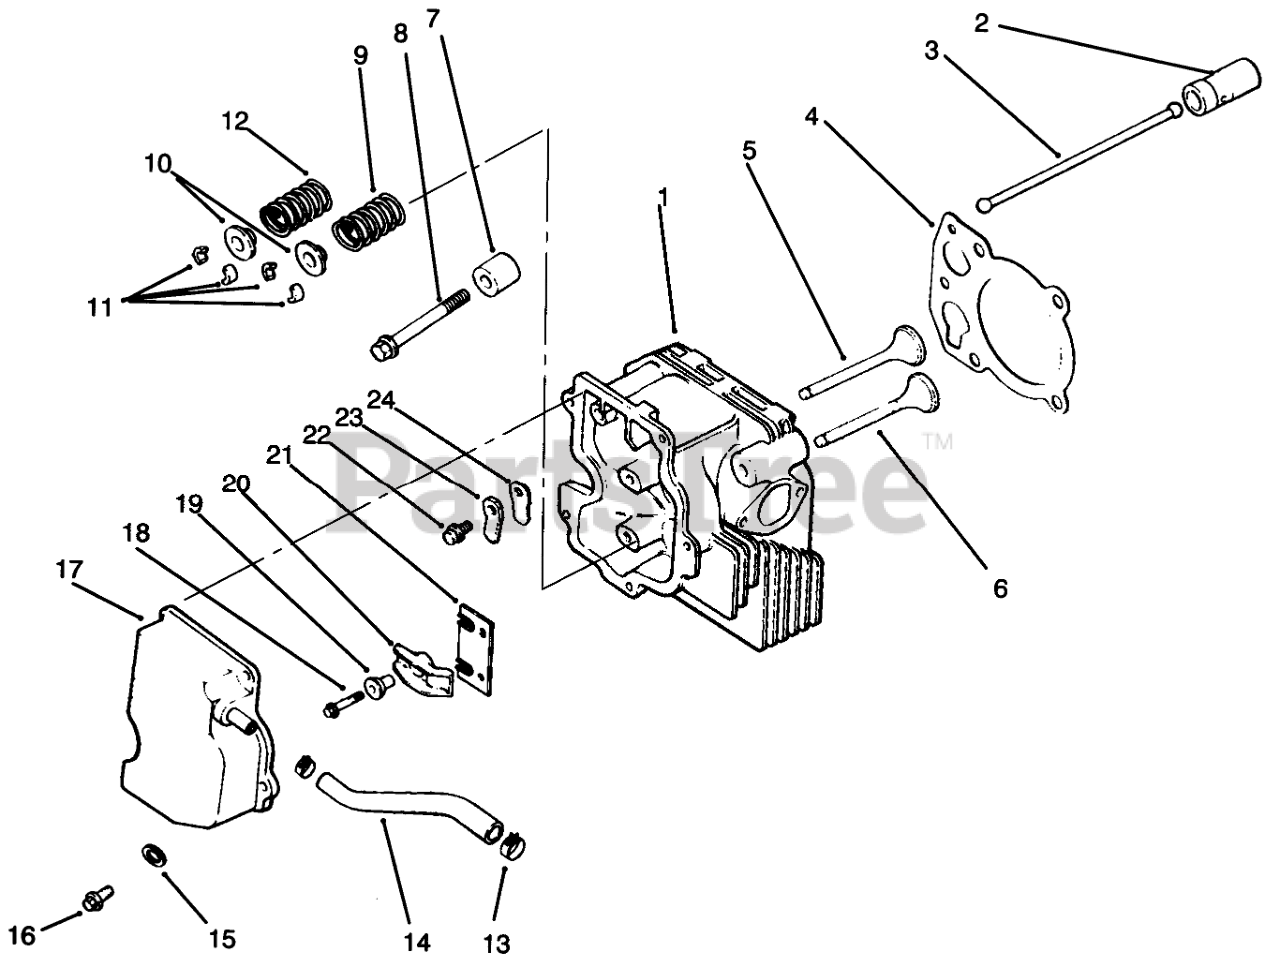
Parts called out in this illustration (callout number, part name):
1	Cylinder Head (Only On: 72042, 72043, 72062, 72063)
2	Lifter-Valve (Only On: 72042, 72043, 72062, 72063)
3	Rod-Push (Only On: 72042, 72043, 72062, 72063)
4	Gasket-Cylinder Head (Only On: 72042, 72043, 72062, 72063)
5	Valve-Intake STD (Only On: 72042, 72043, 72062, 72063)
5	Valve-Intake .25 (Only On: 72042, 72043, 72062, 72063)
6	Valve-Exhaust STD (Only On: 72042, 72043, 72062, 72063)
6	Valve-Exhaust .25 (Only On: 72042, 72043, 72062, 72063)
7	Spacer-Head Bolt Exhaust (Only On: 72042, 72043, 72062, 72063)
8	Screw M10x1.5x80 (Only On: 72042, 72043, 72062, 72063)
9	Spring-Valve Exhaust (Only On: 72042, 72043, 72062, 72063)
10	Cap-Valve Spring (Only On: 72042, 72043, 72062, 72063)
11	Kit-Retainer (Only On: 72042, 72043, 72062, 72063)
12	Spring-Valve Intake (Only On: 72042, 72043, 72062, 72063)
13	Clamp-Hose (Only On: 72042, 72043, 72062, 72063)
14	Hose-Breather (Only On: 72042, 72043, 72062, 72063)
15	Washer-Flat (Only On: 72042, 72043, 72062, 72063)
16	Screw M6x1.0x20 (Only On: 72042, 72043, 72062, 72063)
17	Cover-Valve W/Nipple (Only On: 72042, 72043, 72062, 72063)
18	Screw M6x1.0x34 (Only On: 72042, 72043, 72062, 72063)
19	Ball-Rocker Pivot (Only On: 72042, 72043, 72062, 72063)
20	Arm-Rocker (Only On: 72042, 72043, 72062, 72063)
21	Plate-Guide (Only On: 72042, 72043, 72062, 72063)
22	Screw M5x0.8x10 (Only On: 72042, 72043, 72062, 72063)
23	Retainer-Breather Reed (Only On: 72042, 72043, 72062, 72063)
24	Reed-Breather (Only On: 72042, 72043, 72062, 72063)
